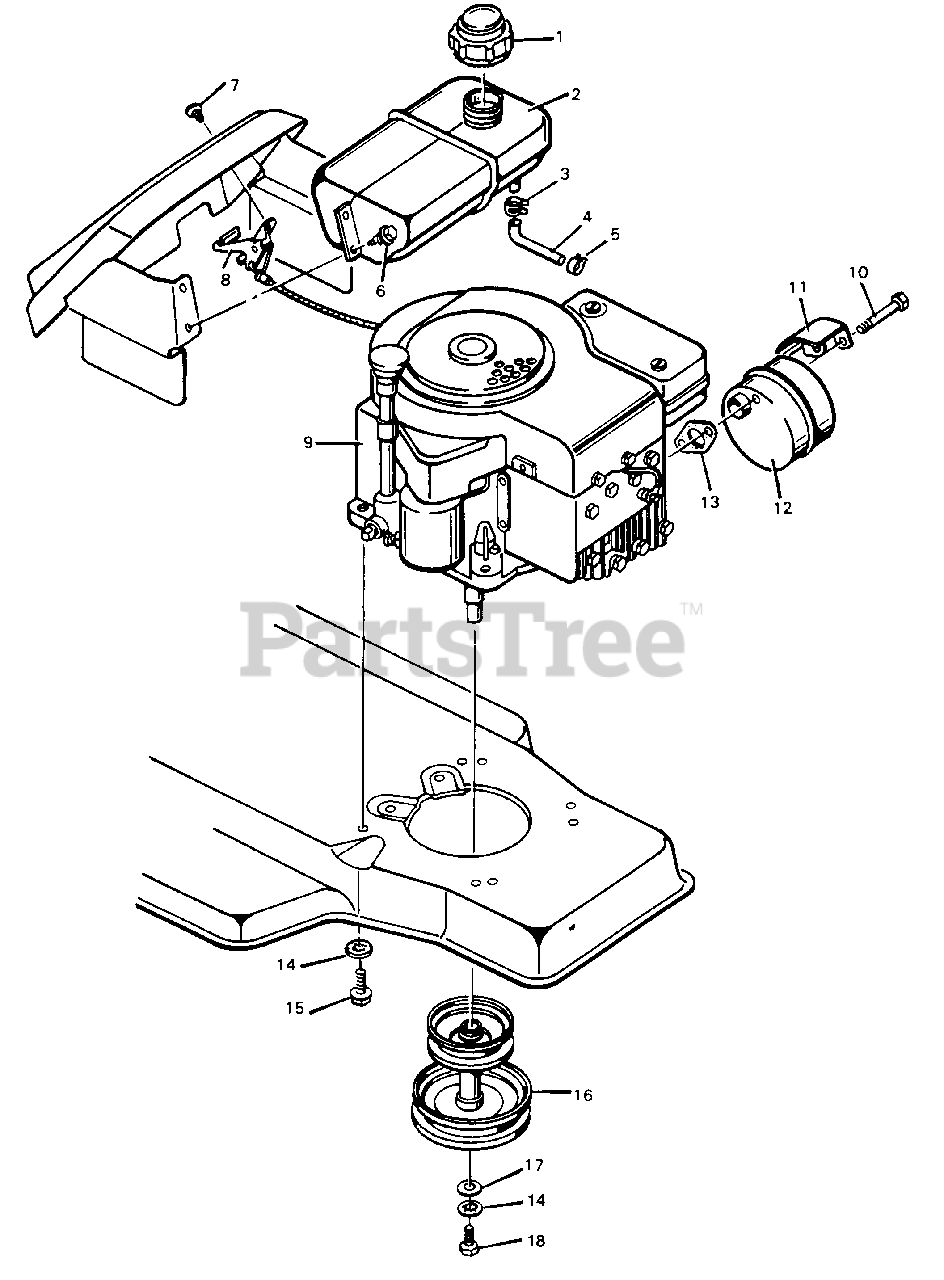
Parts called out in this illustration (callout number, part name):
1	CAP- Fuel
2	TANK- Fuel
3	CLAMP- Hose
4	LINE- Fuel
5	CLAMP- Hose
8	CONTROL- Throttle
9	ENGINE
10	BOLT- Hex
11	SHIELD- Muffler heat
15	BOLT- Engine mount
16	STACK PULLEY ASSEMBLY
18	BOLT- Hex
